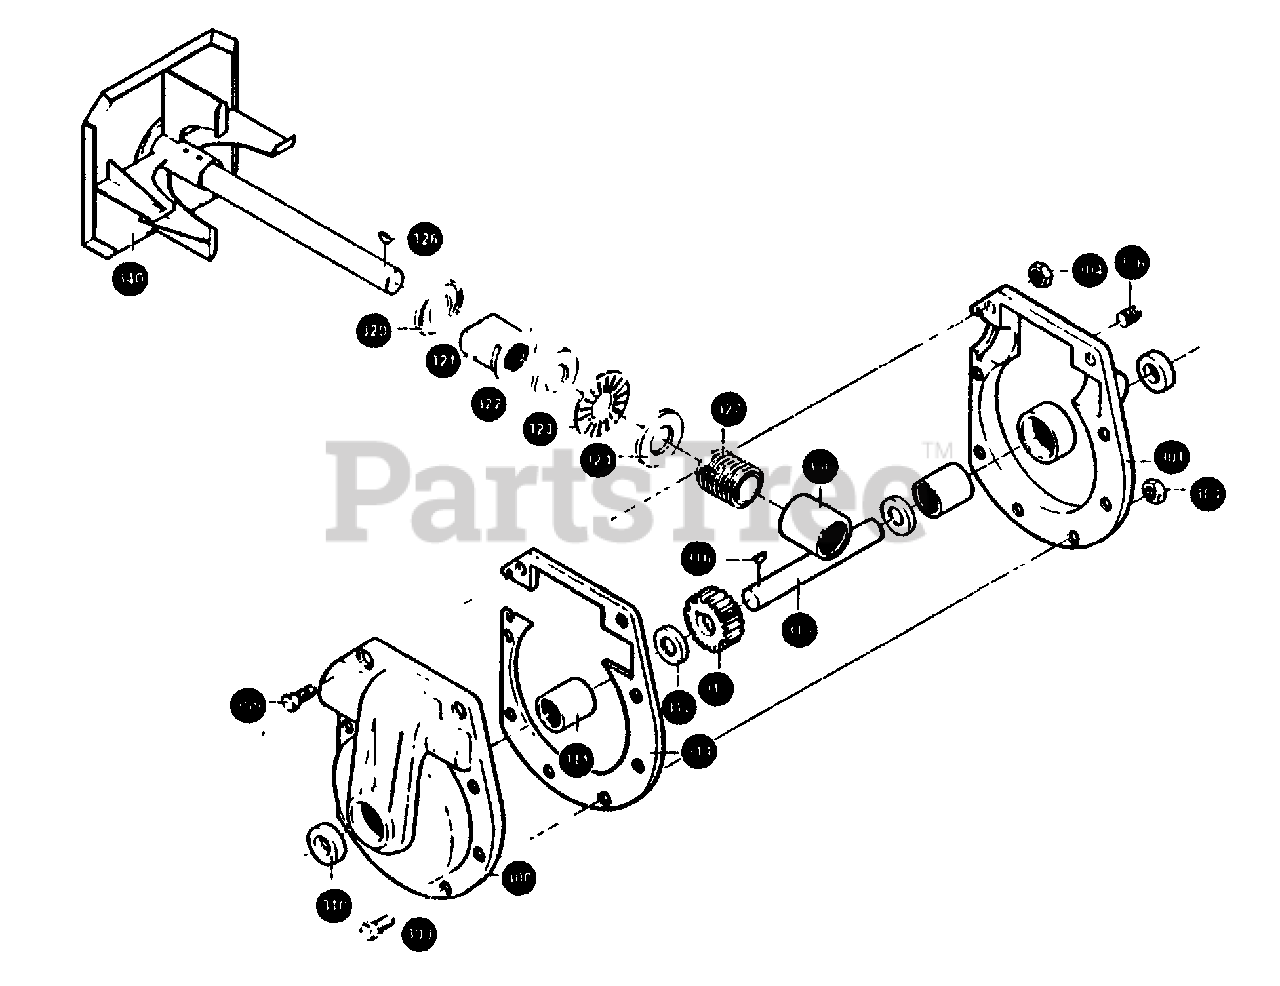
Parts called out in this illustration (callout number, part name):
300	CASE. GEAR RH
301	CASE. GEAR LH
303	SCREW, 5/16-201.00
304	NUT, 5/16-24
305	SCREW, 5/16-24X1.50
311	BEARING. SLEEVE
312	WASHER, FLAT
313	SHAFT, AUGER OUTPUT
314	GASKET, GEAR BOX
320	RING, QUAD
322	FLATWASHER .752X1.24X.093PL
323	BEARING, ROLL
324	FLATWASHER .752X1.24X.093PL
326	KEY. HI-PRO
330	BEARING. SLEEVE
340	IMPEL, ASSY
